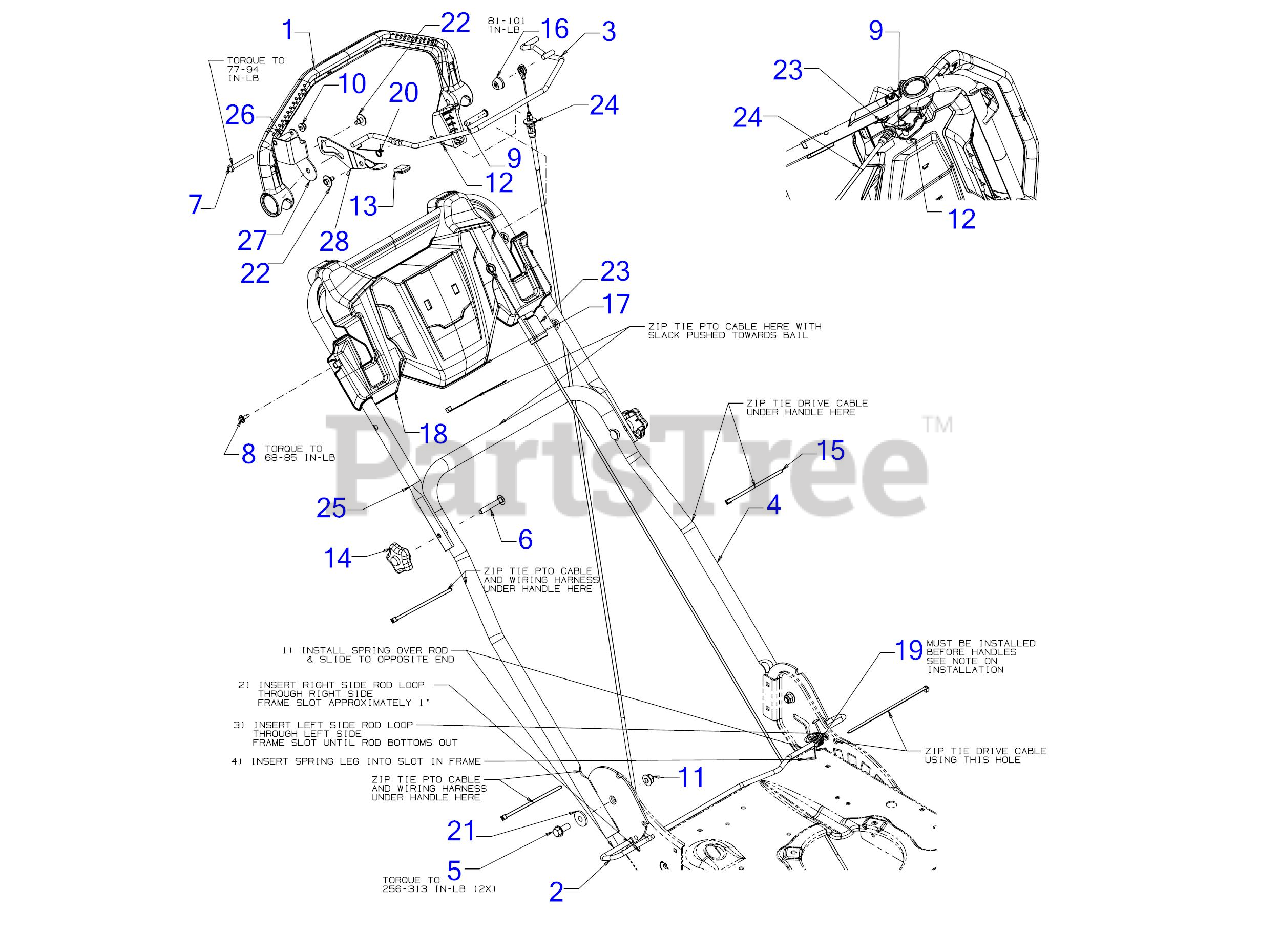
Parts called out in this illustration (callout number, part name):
1	DRIVE HANDLE ASSEMBLY (YELLOW)
2	PIVOT HANDLE ROD
3	PTO STRAIGHT HANDLE BAIL
4	LOWER HANDLE ASSEMBLY
5	SCREW 3/8-16 x .875 GR5
6	CARRIAGE BOLT 5/16-18 x 2.00 GR5
7	SCREW 1/4-20 x 2 GR5
8	SCREW M6-1 x .625
9	CLEVIS PIN 3/8 x 1.87
10	FLANGE LOCK NUT
12	BOW TIE COTTER PIN 1/4-5/16
14	STAR KNOB- YELLOW
15	7" CABLE TIE
16	PUSH CAP 0.3125
17	CONSOLE TRIM PIECE
18	HANDLE CONSOLE
19	TORSION SPRING .48 x .177
20	TORSION SPRING
21	SHOULDER SPACER .625 x .169
22	SHOULDER SCREW
23	DRIVE CABLE
24	CONTROL CABLE
26	SPACER:.260 x .372 x 1.420
27	LOCK OUT PLATE BRACKET (POWDER BLACK)
28	LOCK OUT BRACKET
